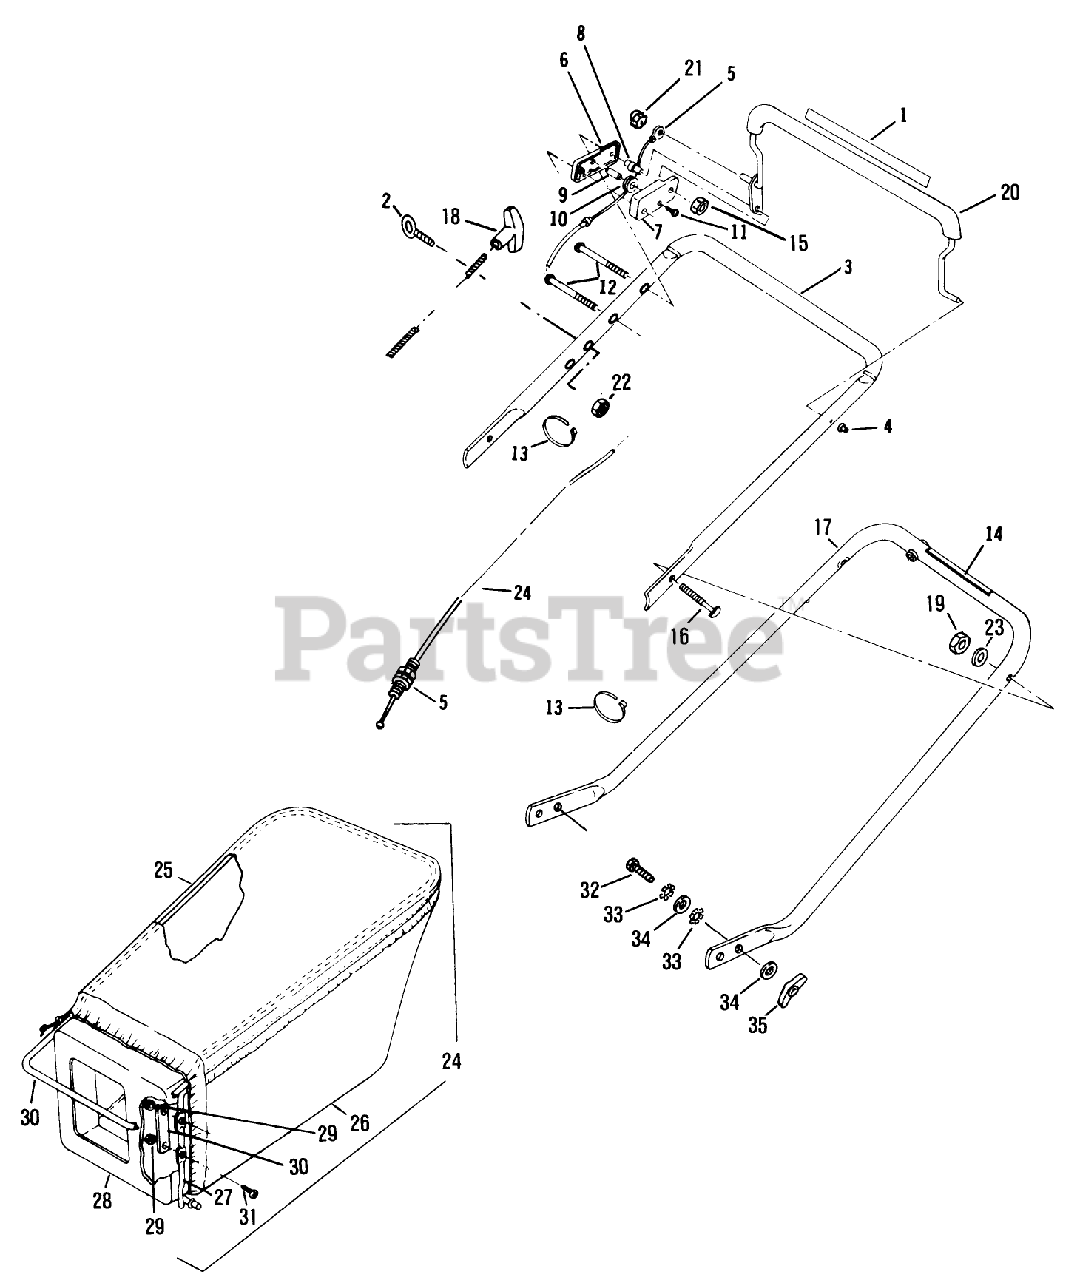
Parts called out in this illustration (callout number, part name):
2	EYE BOLT WAS MFG
8	COLUMN
9	PIN SKF
11	SCREW
15	NUT C/LOCK E
18	HANDLE START UM&D
19	NUT-LOCK F
21	NUT ACORN
22	LOCKNUT E
23	WASHER-CURVED
25	HANGER BAG TROX
28	BAG ADAPTOR PL
29	LOCKNUT E
33	LOCK WASHER LARSON
34	WASHER
35	NUT-WING
